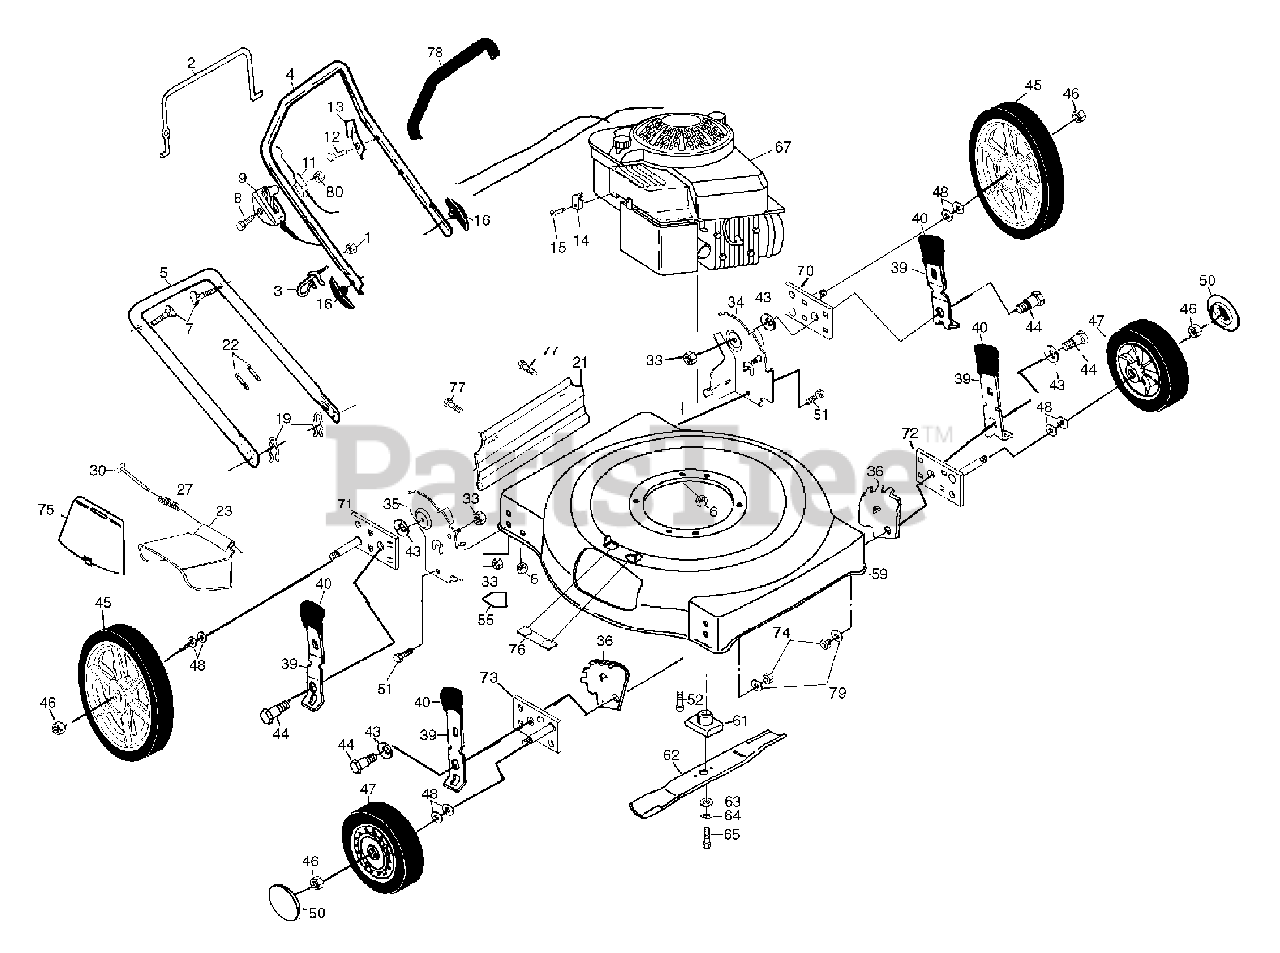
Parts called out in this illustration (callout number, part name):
1	Locknut 1/4-20
2	Control Bar
3	Rope Guide
4	Upper Handle (with Foam Grip)
5	Lower Handle
6	Locknut 1/4-20
7	Handle Bolt 5/16-18
8	Hex Washer Head Screw 1/4-20 x 2-1/8
9	Throttle Control
11	Engine Zone Control Cable
12	Hex Washer Head Screw #10-24 x 1/2
13	Up-Stop Bracket
14	Cable Clamp
15	Screw #10 x 5/8
16	Handle Knob
19	Hairpin Cotter
21	Rear Deflector
22	Wire Tie
23	Discharge Guard
27	Torsion Spring
33	Locknut 5/16-18
34	Wheel Bracket Support (Left)
35	Wheel Bracket Support (Right)
36	Wheel Bracket Adjuster
39	Selector Spring
40	Selector Knob
43	Washer
44	Shoulder Bolt
45	Wheel Assembly (Rear)
46	Locknut 1/16-18
47	Wheel Assembly (Front)
48	Washer
51	Hex Head Bolt 5/16-18x
52	Hex Head Thread Rolling Screw 3/8-16 x 1
55	Danger Decal
59	Lawn Mower Housing
61	Blade Adapter
63	Hardened Washer
64	Helical Lockwasher 3/8
65	Screw Hex Head 3/8-24 x 1-3/8 (Grade 8)
70	Axle Arm Assembly (LR)
71	Axle Arm Assembly (RR)
72	Axle Arm Assembly (LF)
73	Axle Arm Assembly (RF)
74	Nut
75	Plate, Mulcher
76	Clip, Closeout
78	Foam Grip
79	Washer
80	Nut, Hex 1/4-20
